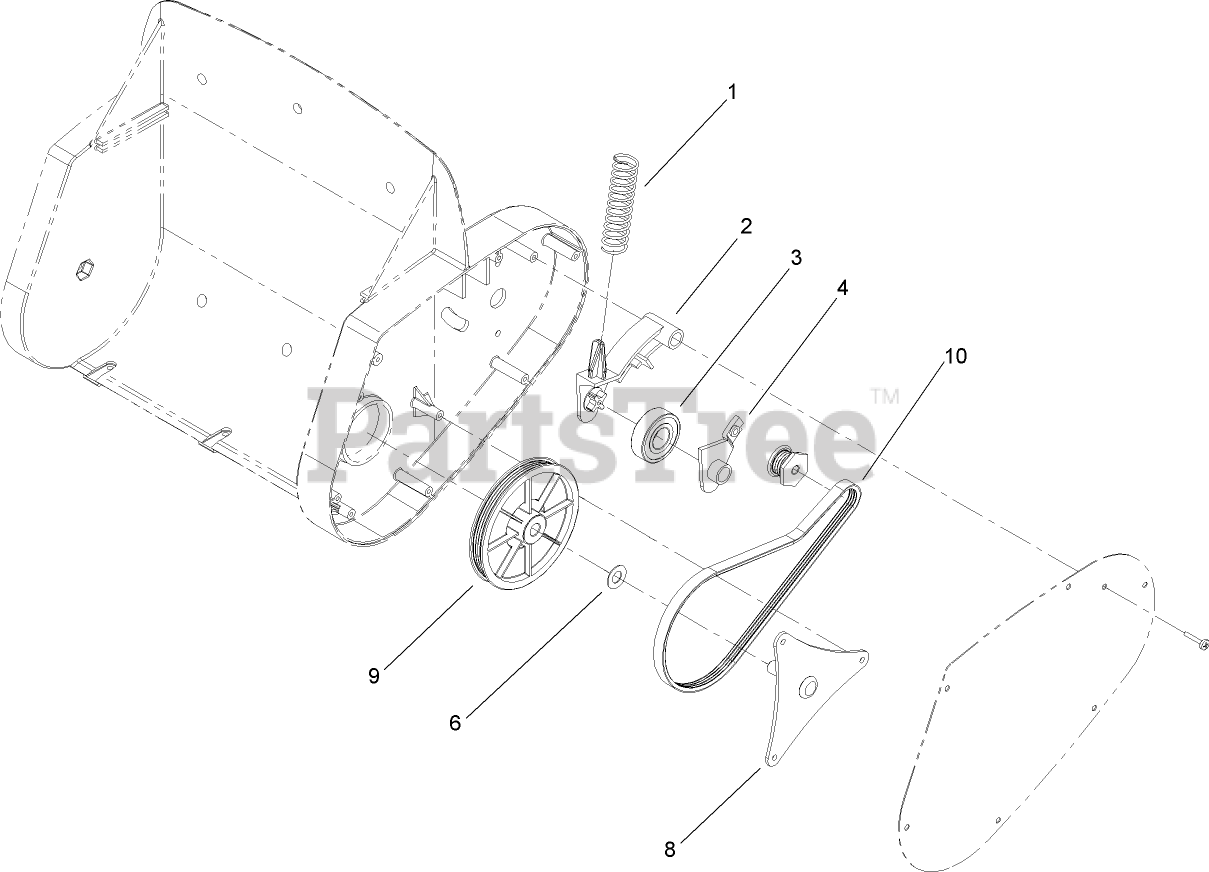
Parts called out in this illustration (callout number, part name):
1	SPRING
2	ARM-IDLER
3	BEARING-BALL
4	RETAINER-PULLEY, IDLER ARM
6	WASHER-PLAIN
8	PULLEY BRACKET ASM
9	PULLEY ASM
10	BELT-DRIVE
